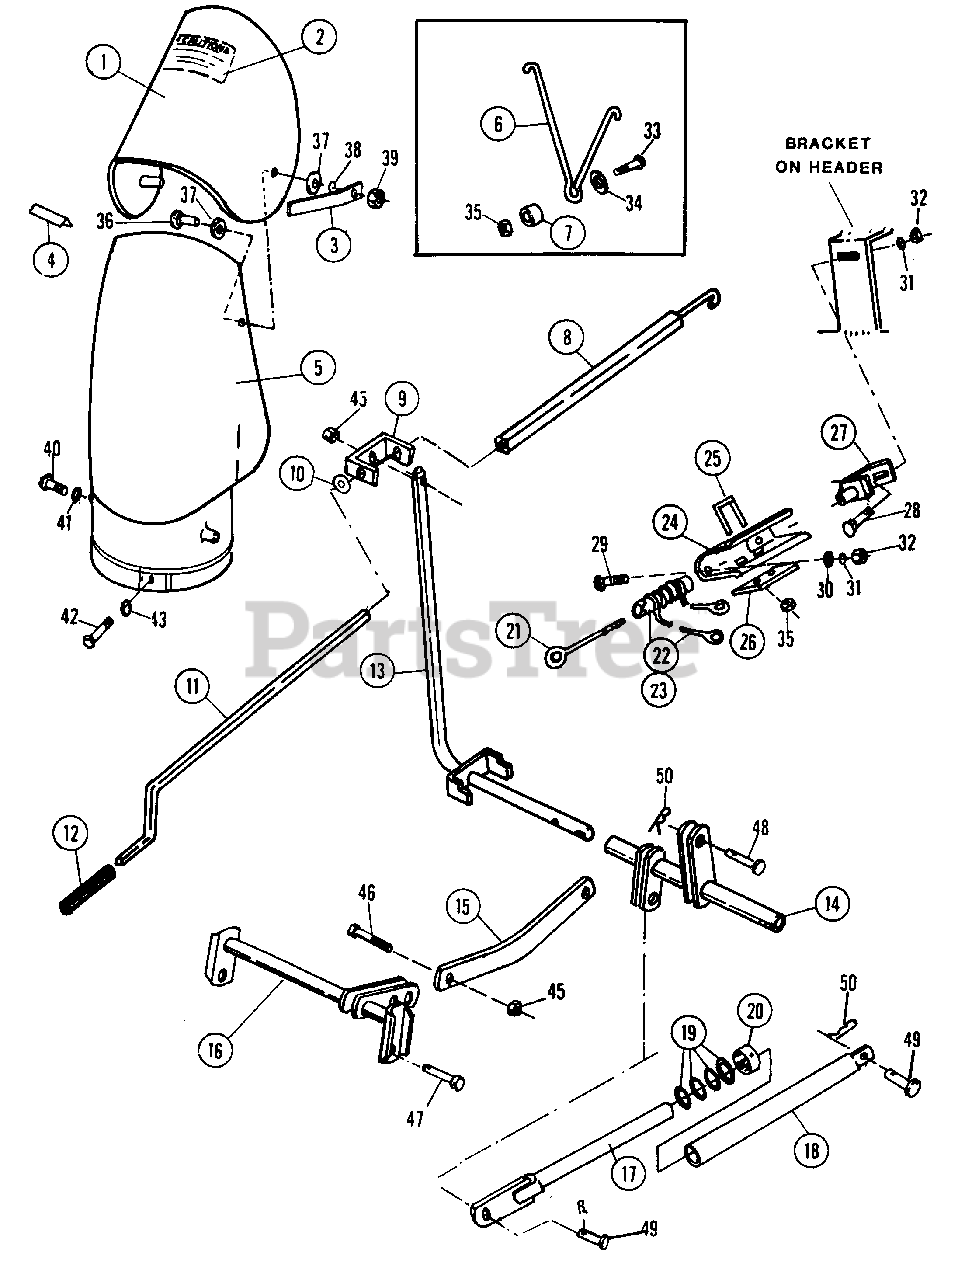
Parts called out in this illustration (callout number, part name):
1	DEFLECTOR, DISCHARGE
2	DECAL, WARNING (SPINNING BLADES)
3	STRAP, DEFLECTOR LOCKING
4	MOLDING, RUBBER
5	CHUTE, DISCHARGE
6	GUARD, SPRING HOOK
7	SPACER, SPRING HOOK
8	EXTENSION, CRANK ROD
9	GUIDE, CRANK ROD
10	DECAL, CHUTE CONTROL
11	ROD, CRANK CONTROL
12	GRIP, CRANK CONTROL HANDLE
13	SUPPORT, CRANK ROD
14	LINKAGE LIFT
15	STRAP, LINK
16	LINKAGE, BELLCRANK
17	ROD, LIFT
18	TUBE, LIFT
19	WASHER, LIFT STOP ADJUSTING
20	COLLAR, LIFT TUBE
21	EYE-BOLT
22	CABLE-TUBE ASSEMBLY
23	TUBE, CHUTE DRIVE
24	SHROUD, CHUTE DRIVE
25	U-BOLT, LEVEL WIND
26	STRAP, LEVEL WIND FRICTION
27	BRACKET, CHUTE DRIVE MOUNTING
28	BOLT, 3/8cx3/4 CARRIAGE
29	BOLT, 3/8cx1" CARRIAGE
30	WASHER, 3/8" Flat
31	LOCKWASHER, 3/8
32	NUT, 3/8 C HEX
33	BOLT, 1/4cx1-1/4 HEX HEAD
34	WASHER, SPECIAL RETAINER
35	LOCKNUT, 1/4C HEX
36	BOLT, 5/16-18x1" CARRIAGE
37	WASHER, DEFLECTOR
38	LOCKWASHER, 5/8"
39	LOCKNUT, 5/8c HEX
40	BOLT, 1/4-20x1-1/2 HEX HEAD
41	WASHER, CABLE RETAINING
42	BOLT, 1/4-20x5/8 HEX HEAD
43	LOCKWASHER, 1/4"
45	LOCKNUT, 3/8-16 HEX
46	BOLT, 3/8-16x1-1/4 HEX HEAD
47	CLEVIS, PIN
48	CLEVIS-PIN
49	CLEVIS-PIN
50	HAIR PIN, COTTER
